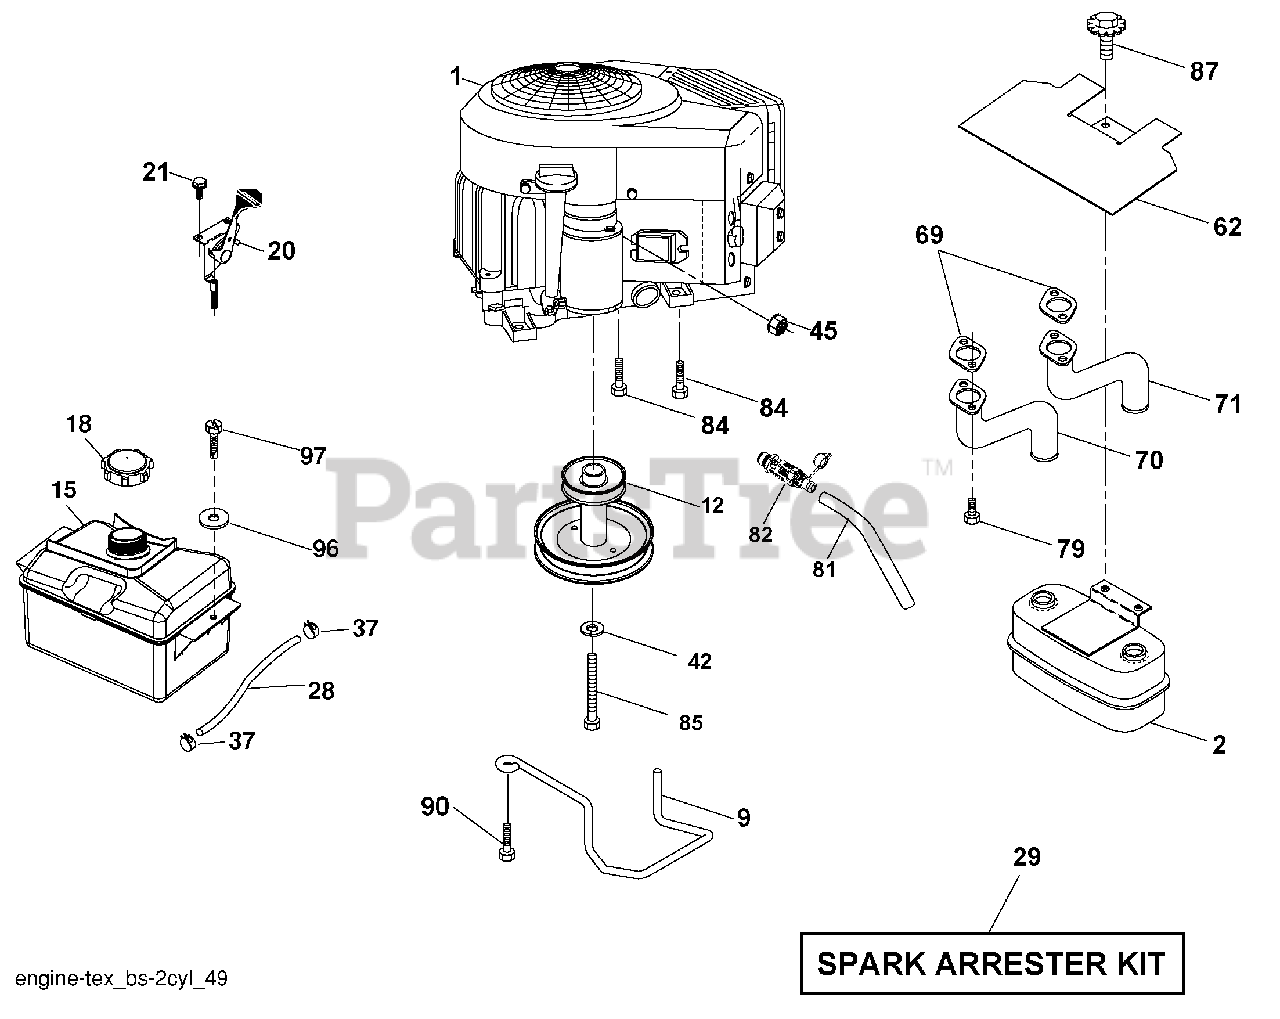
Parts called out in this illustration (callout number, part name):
9	Keeper Belt Engine
12	Pulley Engine
15	Tank Fuel
18	Cap Asm
20	Control Throttle/Choke
21	Screw #10 x 0.750 BOS Thread
28	Fuel Line
29	Spark Arrester Kit
37	Clamp Hose
42	Washer Lock 7/16
45	Nut Keps Hex 1/4-20 unc
62	Shield Heat
70	Exhaust Tube LH
71	Exhaust Tube RH
79	Screw 5/16-18 x 1
81	Tube Drain Oil Easy
82	Valve Drain Oil
84	Screw 3/8-16 x 1/4
85	Bolt Hex 7/16-20 x 4 Gr. 5
87	Bolt 5/16-18 unc x 3/4 w/sems
90	Screw 3/8-16 x 1
96	Washer 9/32 x 7/8 x 16 Ga.
97	Screw 1/4-20 x 3/4
